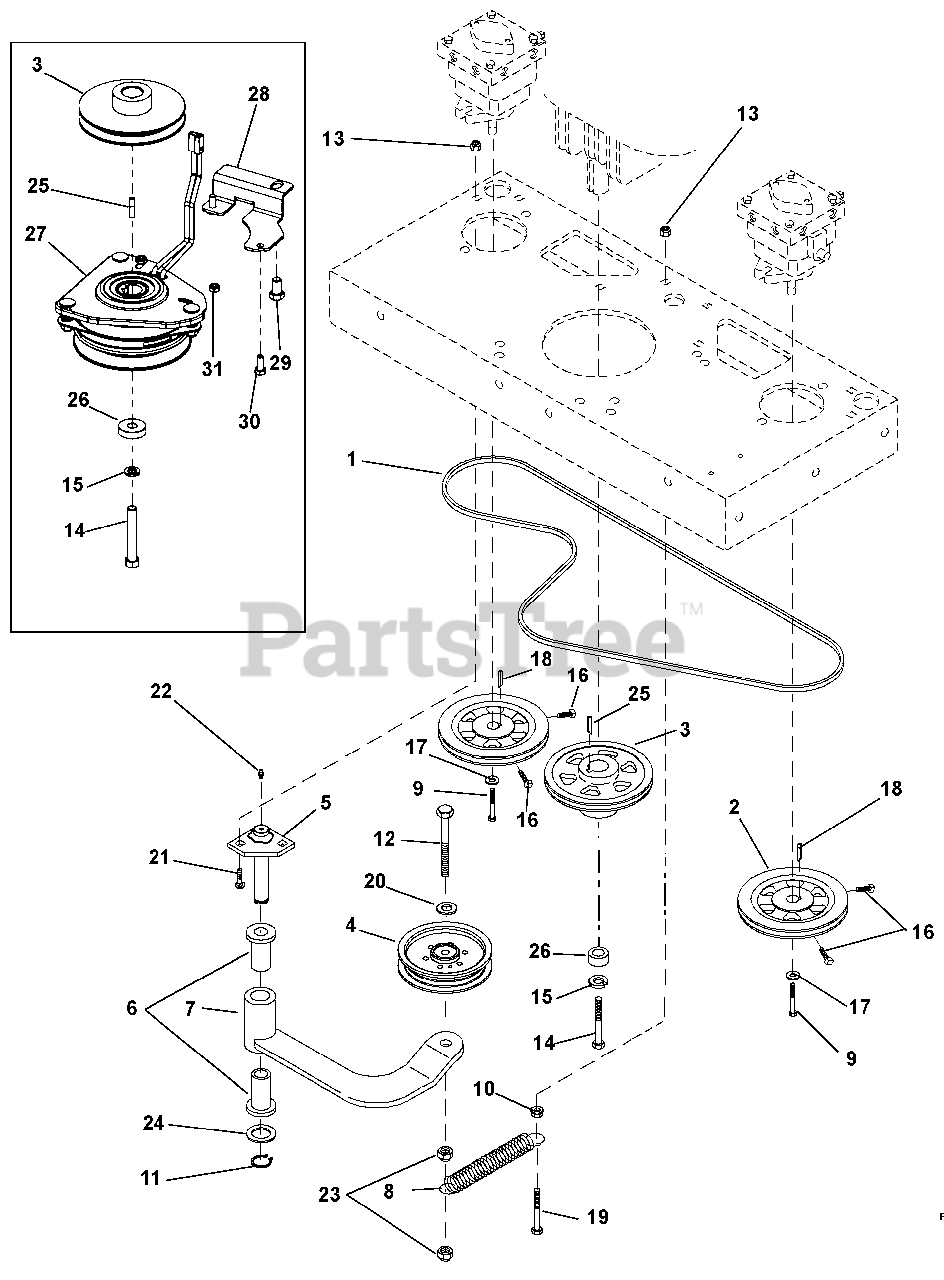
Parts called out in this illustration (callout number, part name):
1	Belt, Drive, Pump
2	Assembly, Pump Pulley w/ Set Screw
4	Assembly, Idler 4
5	Weldment, Pivot Idler Mount
6	Bushing
7	Arm, Idler Weldment
8	Spring, External
9	Bolt, M6 x 1.00 x 10 Hex
10	Locknut, M10 x 1.50
11	Ring, Snap, External .750 x .042
12	Bolt, Hex .38-16 x 2.50
13	Nut, Locking, Nylon M10-1.5
14	Bolt, Hex .44-20 x 3.00 Grade 5 EP80
15	Washer, Locking .44 x .109
16	Set Screw
17	Washer, Locking .250 x .077
18	Key, Special M5 x 28
19	Cap Screw, Spring Anchor, M10
20	Washer, Flat .406 x .812 x .065
21	Carriage Bolt, M10 x 1.5 x 25
22	Lubrication Fitting
23	Nut, Locking, Center .38-16
24	Bushing, 3/4 Machine
25	Key, .250 x .250 x .995 Taper
27	Clutch Assembly, Ogura
28	Plate, Clutch Dog
29	Bolt, 7/16-14 x .750 Hex 5 (994100)
30	Bolt, Hex .31-18 x .75 Grade 5 (994100)
31	Nut, Locking, Nylon .312-18 (994100)
